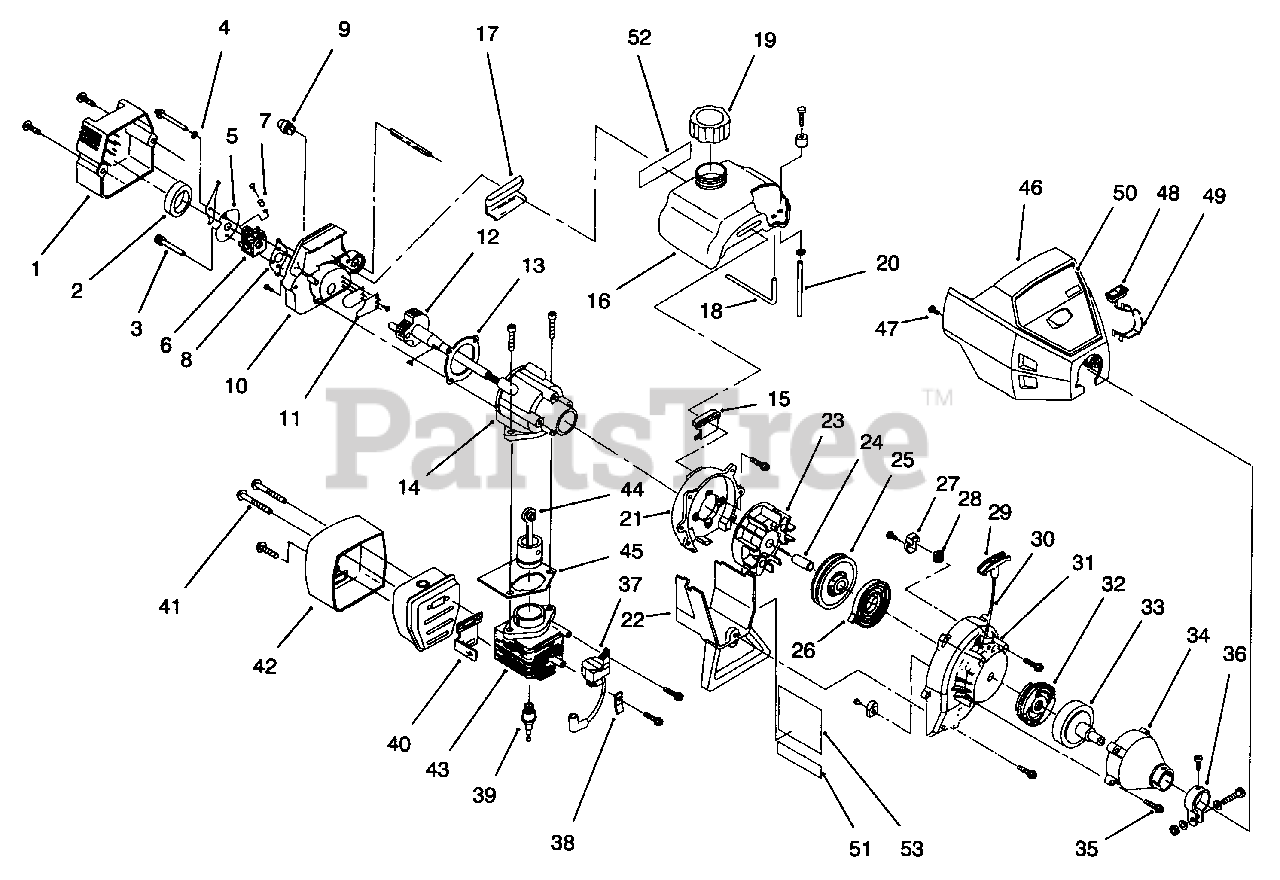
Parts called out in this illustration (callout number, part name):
1	Carburetor/Air Cleaner Asm. (Incl. Ref. #2)
2	Air Cleaner Filter
3	Carburetor Mounting Screw Asm.
4	Wavey Washer
5	Choke Lever & Plate
6	Carburetor Asm.
7	Throttle Adj. Asm. (Walbro)
7	Throttle Adj. Asm. (Zama)
8	Carburetor Gasket
9	Primer & Hose Asm.
10	Carburetor Mount Asm.
11	Reed Asm.
12	Power Shaft Asm.
13	Carburetor Mount Gasket
14	Crankcase Service Asm. (Incl. Ref. #12)
15	Front Mounting Pad
16	Fuel Tank Asm. (Incl. Ref. #18-20)
17	Rear Mounting Pad
18	Return Line
19	Fuel Cap Asm.
20	Fuel Line Asm.
21	Shroud Asm.
22	Shroud Extension & Stand
23	Flywheel Asm.
25	Recoil Pulley Asm.
26	Recoil Spring
27	Pulley Retainer Asm.
28	Rope Guide
29	Pull Handle
31	Starter Housing Asm.
32	Clutch Rotor Asm.
33	Clutch Drum Asm.
34	Clutch Cover Asm.
35	Clutch Cover Screw Asm.
36	Upper Clamp Asm.
37	Module Asm.
38	Ground Tab
39	Spark Plug
40	Exhaust Gasket
41	Muffler Mounting Bolt Asm.
42	Muffler Asm. (Incl. Ref. #41)
43	Cylinder Asm.
44	Piston and Rod Asm.
45	Cylinder Gasket
46	Engine Cover
47	Engine Cover Screw
49	Lead Wires
50	Decal-Toro Housing
51	Decal-Warning
52	Decal-Fuel & Oil Mix
52	Decal-Carb.
